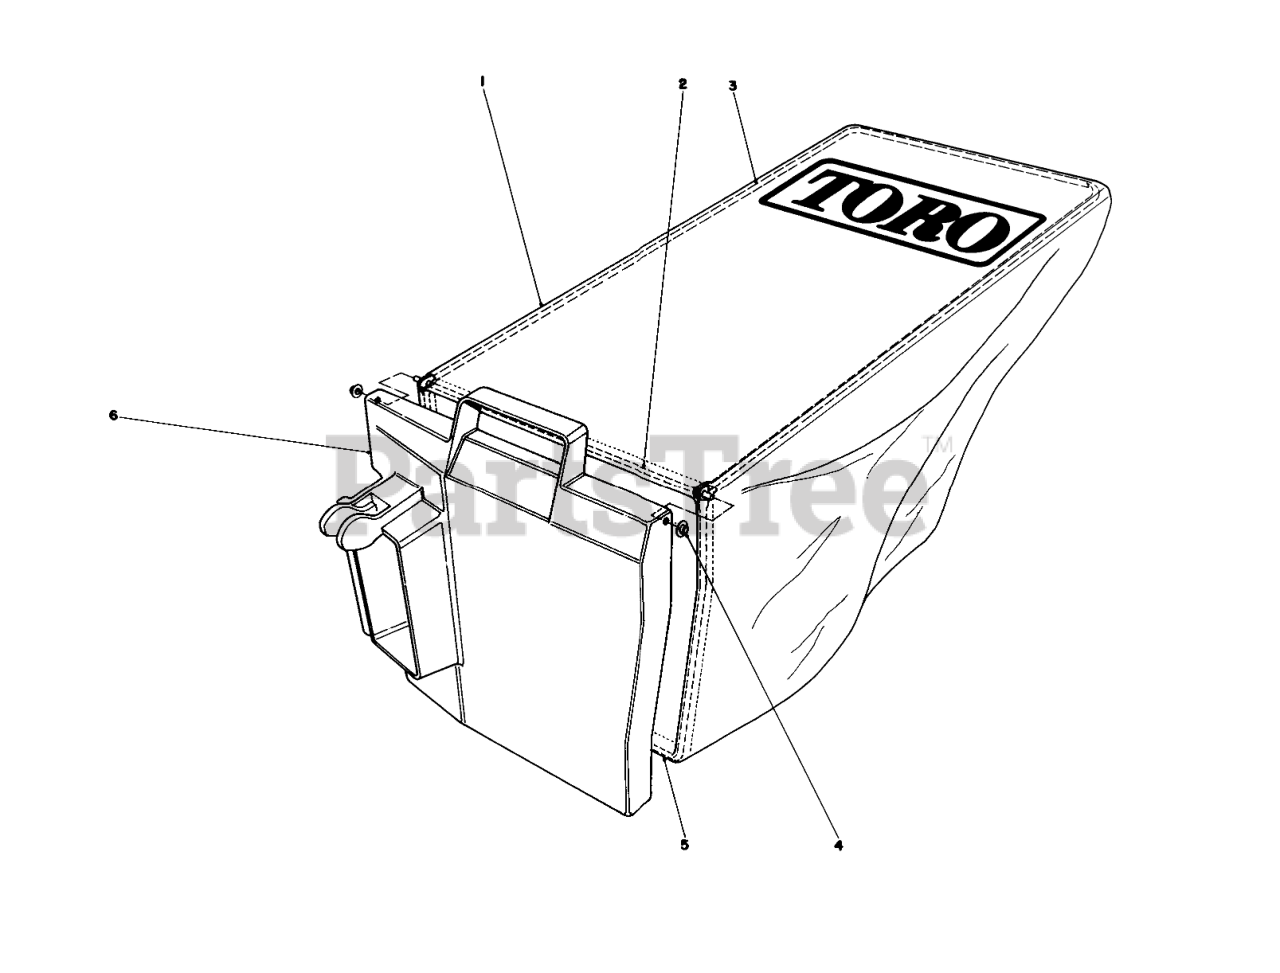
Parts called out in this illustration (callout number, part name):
1	18 BAGGER BAG 33-4552
2	HINGE PIN
3	BAG FRAME-UPPER
4	NUT-PUSH
5	Frame Bag
6	Door-Bag
